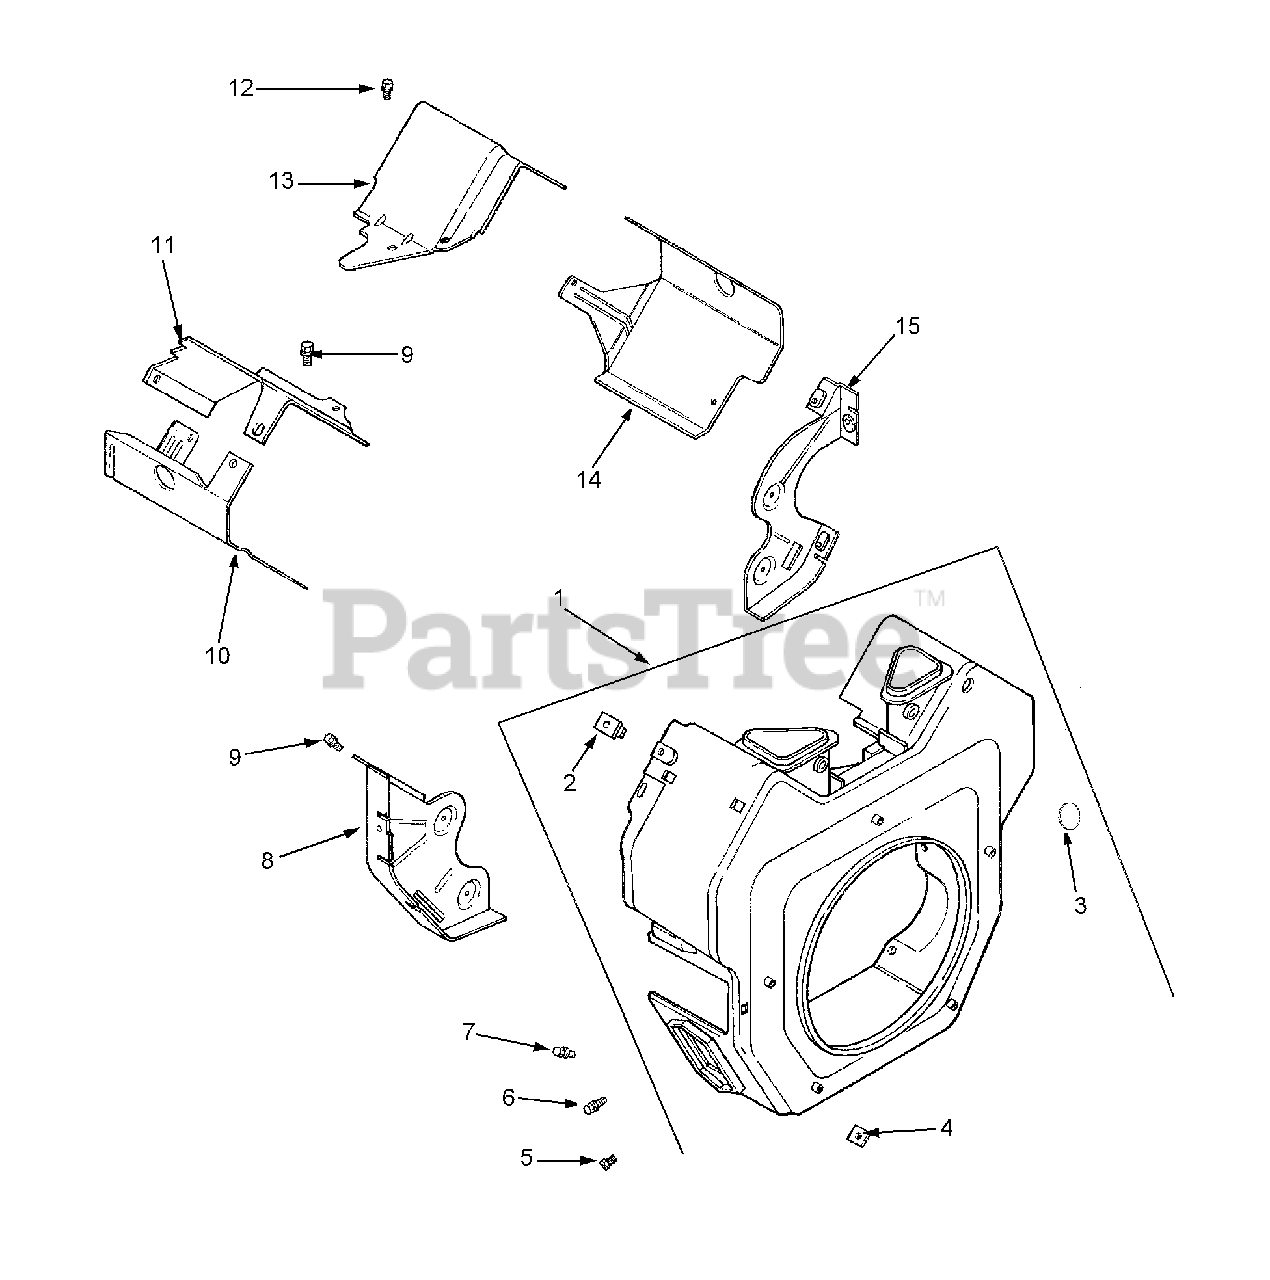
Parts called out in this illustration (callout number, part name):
1	Housing, Blower
2	Nut, Plastic
3	Plug, Button 9/16"
4	Nut, Plastic
5	Screw, Hex Flange M5 x 0.8 x 16
6	Screw, Hex Flange M5 x 0.8 x 16
7	Screw, Hex Flange M5 x 0.8 x 20
8	Plate, Backing #2 Side
9	Screw, Hex Flange M6 x 1.0 x 16
10	Baffle, Cyl. Barrel #2 Side
11	Baffle, Valley #2 Side
12	Screw, Hex Flange M5 x 0.8 x 10
13	Baffle, Valley #1 Side
14	Baffle, Cyl. Barrel #1 Side
15	Plate, Backing #1 Side
